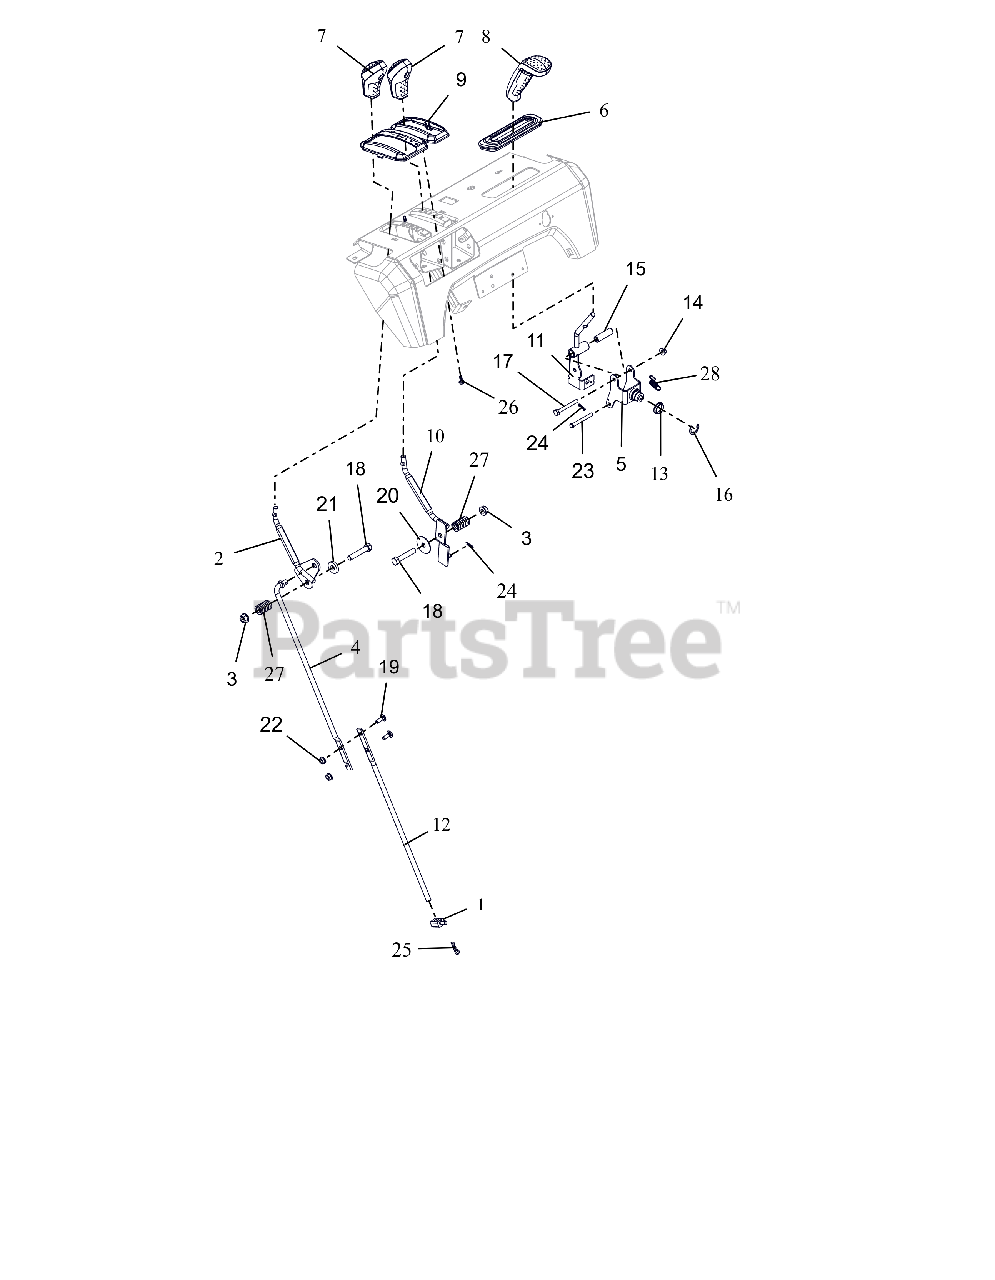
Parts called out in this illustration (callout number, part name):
1	PIVOT,SHIFT ROD .375-16(TRUNN)
2	WELDMENT,LG DASH SPEED CONTROL
3	NUT-LK-TOP-FLG .38-16 ZC120
4	ROD, SHIFT - UPPER
5	WELDMENT, CONTROL BRACKET
6	GROMMET, BOOT, QUICK TURN
7	KNOB, CONTROL, DASH
8	HANDLE, QUICK TURN, ASM
9	BEZEL, SHIFT - FRICTION SNOW
10	WELDMENT,LG DASH DEFL CONTROL
11	WELDMENT, CONTROL LEVER
12	ROD, SHIFT-LOWER (LG DASH DLX)
13	BUSHING, POLYLINER-.75 SNAPIN
14	NUT-LK-TOP-FLG .250-20 GF ZCC
15	BSHG, SLV .265X.505X1.665
16	E-RING .750X.050
17	BLT,HEX .25-20X2.25 G5 ZCC
18	BLT,HEX .38-16X2.00 G5 ZCC
19	BLT, RHSN .25-20X.750 G5 ZCC
20	WSHR,FLT .380X1.50X.062 ZCC
21	WSHR, FLT .406X1.00X.188 ZCC
22	NUT-LK-CTR-FLG .25-20 ZC120
23	PIN, CLEVIS - .25 X 2.25 ZCC
24	PIN-HAIR INT .06X.18X.77
25	PIN-HAIR INT .08X.18X1.18 YWZC
26	SCR-TAP #10X.50 BOSS INDHXHD
27	SG-COMP .125X.781X1.250
28	SPRING-EXT .047X.438X1.45
